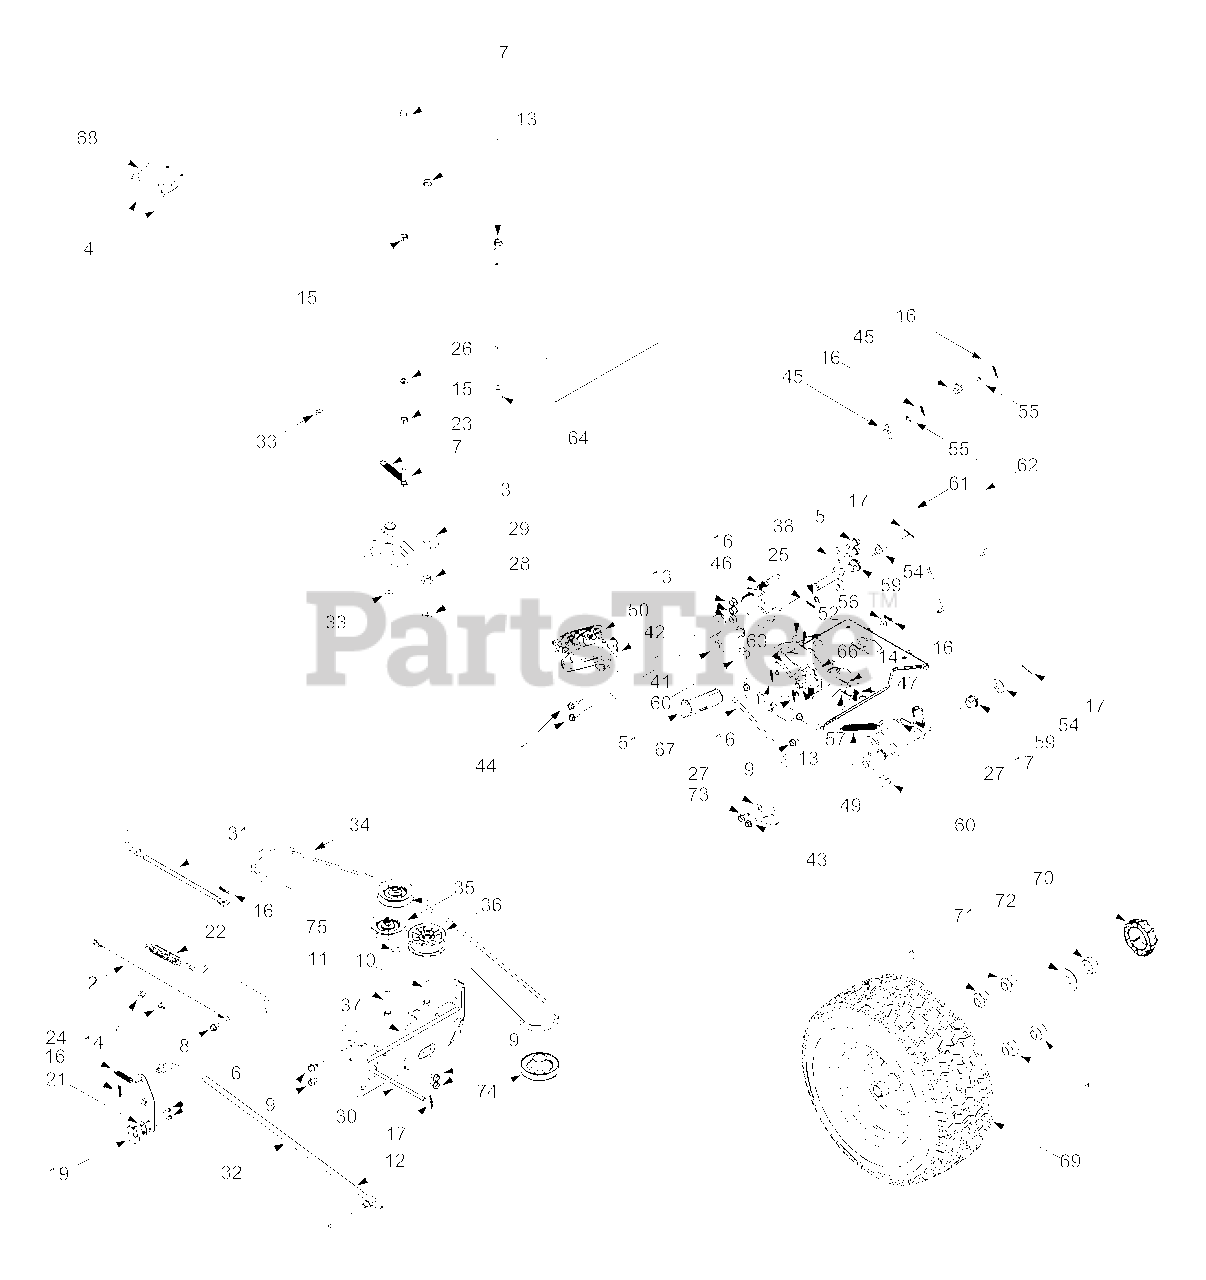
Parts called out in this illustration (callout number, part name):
1	Lug Nut, 3/4-16
2	Reverse/Ground Wire Harness Adapter
4	Hex Cap Screw, 5/16-18 x 2.75
5	Hex Cap Screw, 3/8-16 x .75
6	Screw, #8-18 x .5
7	Hex Cap Screw, 3/8-16 x 1.5
8	Self-tapping Screw, 1/4-20 x .50
9	AB Screw, 5/16-12 x .75
10	Hex Cap Screw, 3/8-16 x 2.25
11	Tt Sems Screw 3/8-16 x 1.5
12	Ferrule
13	Flange Lock Nut, 3/8-16
14	Flange Lock Nut, 5/16-18
15	Hex Nut, 3/8-16
16	Internal Cotter Pin
17	Cotter Pin
18	Cable Tie
19	Short Spring Switch
20	Cable Tie
21	Insulator Nut Plate
22	Extension Spring, .59 x 4.0
23	Extension Spring, .5 x 3.97
24	Extension Spring, 3/8 x 1.44
25	Flat Washer, .385 x .62 x .063
26	Lock Washer, 3/8
27	Flat Washer, .344 x .750 x .120
28	Flat Washer, .407 x .812 x .135
29	Shoulder Spacer, .38
30	Hydrostatic Control Rod
31	Hydrostatic Bypass Rod
32	Hydrostatic Brake Rod
33	Spacer, .376 x .625 x .22
34	Drive Belt
35	V-idler Pulley, 3.06
36	Flat Idler Pulley, 2.75
42	Hydro Pedal Assembly
43	Self-tapping Screw, 5/16-18 x .875
44	Self-tapping Screw, 5/16-18 x .75
45	Ferrule, 1/4-20
46	Pin, 3/8-16 x 2.43
47	Compression Spring, .40 OD x 1.17
48	Extension Spring, .50 OD x 1.41
49	Extension Spring, .50 OD x 6.37
50	Drive Pedal Pad
51	Brake Pedal Pad
52	Flat Washer, .411 x 1.25 x 1.0
53	Flat Washer, .281 x .50 x .063
54	Flat Washer, .64 x 1.24 x .06
55	Flat Washer, .344 x .062 x .03
56	Flat Washer, .406 x .875 x .105
57	Shoulder Screw, .437 x 1.62
58	Shoulder Screw, .5 x .434
59	Hex Flange Bearing
60	Split Hex Flange Bearing
61	Cruise Control Rod
62	Brake Lock Control Rod
63	Cruise Latch
64	Spacer, 5/16 x 1.54
66	Drive Lockout Bracket
70	Hub Cap
71	Flat Washer, .780 x 1.59 x .062
72	Jam Nut, 3/4-16
73	Self-tapping Screw, 5/16-18 x .75
74	Engine Pulley
75	Lock Nut 3/8-16
